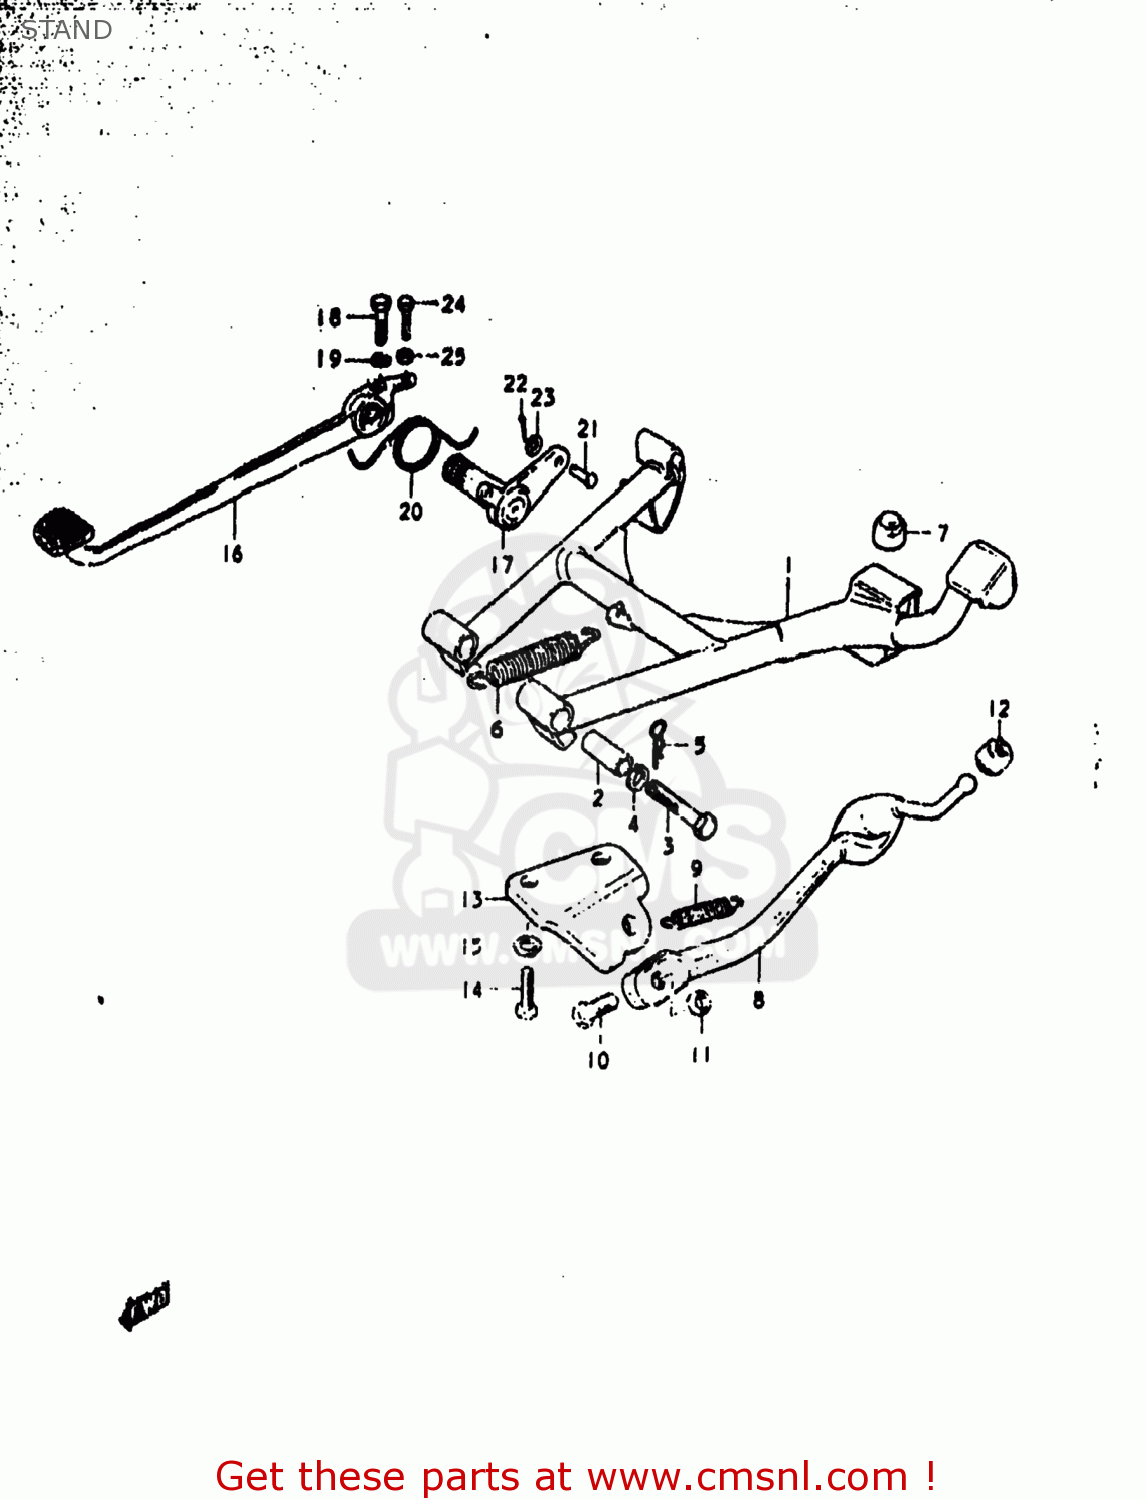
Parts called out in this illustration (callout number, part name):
1	STAND,CENTER
2	SPACER(10X16X38.8)
3	BOLT
4	LOCK WASHER
5	CLIP
6	SPRING
7	CUSHION
8	STAND,PROP
9	SPRING
10	BOLT(10X30)
11	NUT
12	CUSHION
13	BRACKET,SIDE STAND
14	BOLT
15	LOCK WASHER
16	PEDAL,BRAKE
17	ARM,BRAKE PEDAL
18	BOLT
19	LOCK WASHER
20	SPRING
21	PIN
22	PIN
23	WASHER
24	BOLT
25	NUT
